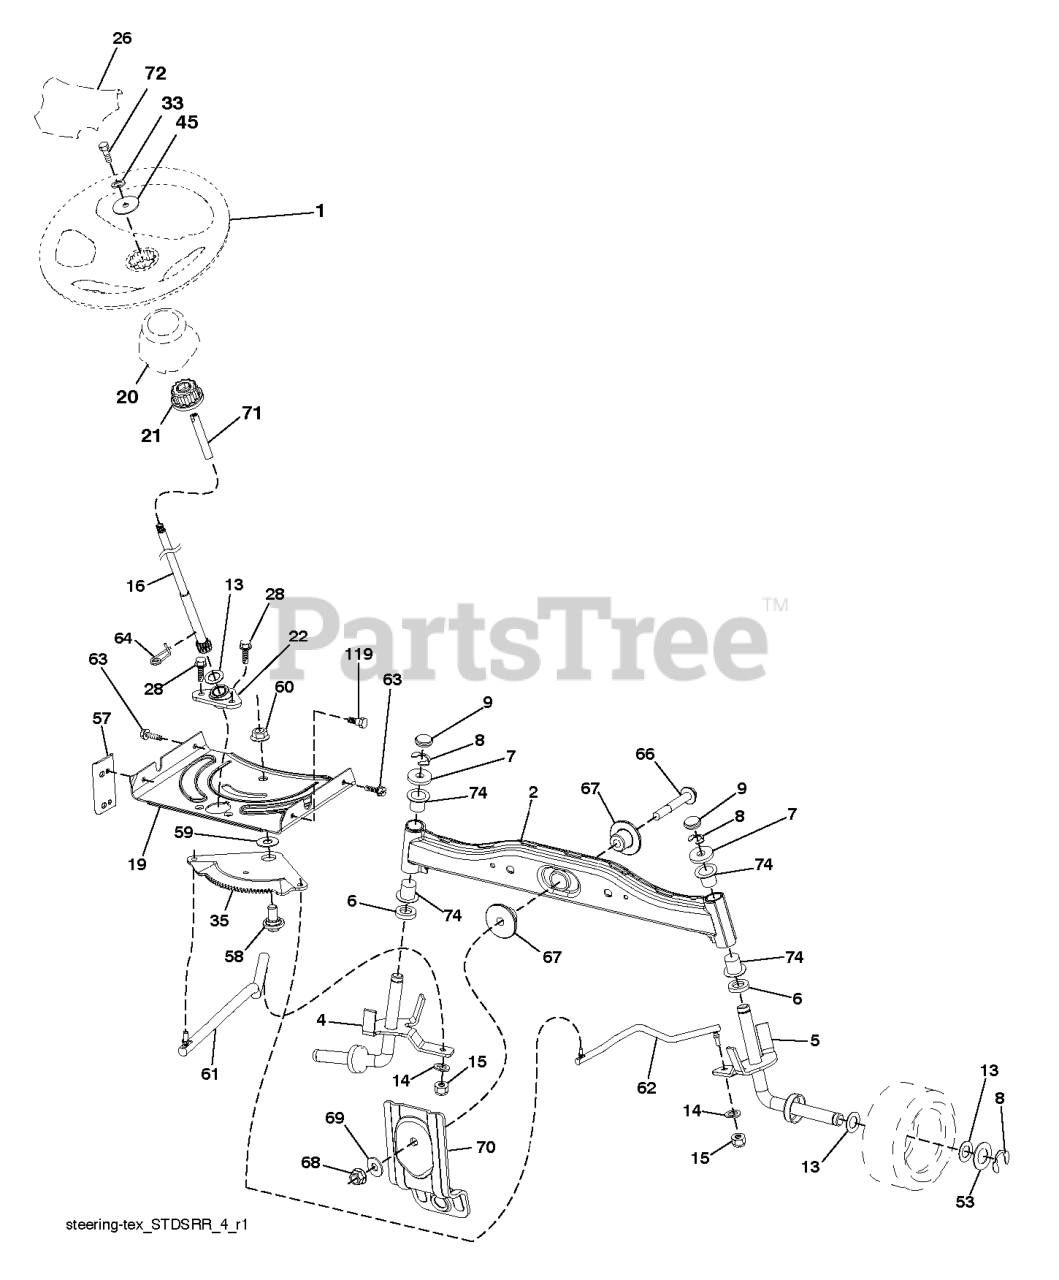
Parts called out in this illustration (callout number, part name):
1	DECK W/DECALS 61" HUS
2	FOOTREST ORANGE
3	ANTI-SKID PAD
4	KNOB W/STUD
5	FOOT PLATE
6	GROMMET, BUMPER
7	CONSOLE WLD
8	FUEL CAP ANTI-SPLASH
10	STUD, 5/16C
11	FUEL TANK RT
12	U-CLIP 5/16-18 NUT RETAINER
13	WASHER.LOCK.HVY.HLCL.SPR.5/16
14	NUT 5/16 NYLOC
15	HCS 5/16C X 1
16	SKID PLATE
17	ENGINE GUARD
18	ENGINE SHROUD BRKT
20	STRUT MOUNT WELDMENT
21	STRUT, RIGHT
23	HYDRAULIC CAP
24	BATTERY HOLD DOWN
25	WASHER 1/4 FLAT
26	HCS 1/4C X 3/4 HCS
27	SEAT BRKT W/DECAL
28	IGNITION SWITCH KIT
29	WASHER 5/16 FLAT
31	WASHER 1/4 FLAT
32	DIGITAL HOUR METER
33	HCS 1/4C X 3/4 HCS
34	SCREW 1/4 X 5/8
35	LOCKWASHER 1/4"
36	RP.SWITCH, BLADE
37	STUD/PLATE MOUNT
38	TANK MOUNT
39	TANK MOUNT
40	NUT.1/4-20.HEX.NYLOC.ZD
42	HCS 5/16C X 3/4
43	NUT 5/16C CENTERLOCK
45	RHSSNB 5/16C X 1.0
46	HCS 5/16C X 4
47	CHOKE CONTROL, COMPLETE
539102650	HOSE BARB 90 DEGREE
539102679	FUEL VALVE
539103275	THROTTLE CABLE
539104409	LEFT TANK W/CUP HOLDER
539105281	FUEL LINE 29.5"
539105527	FUEL LINE 24"
539105530	FUEL LINE 34"
539108351	STRUT, LEFT
539912222	HOSE CLAMP
